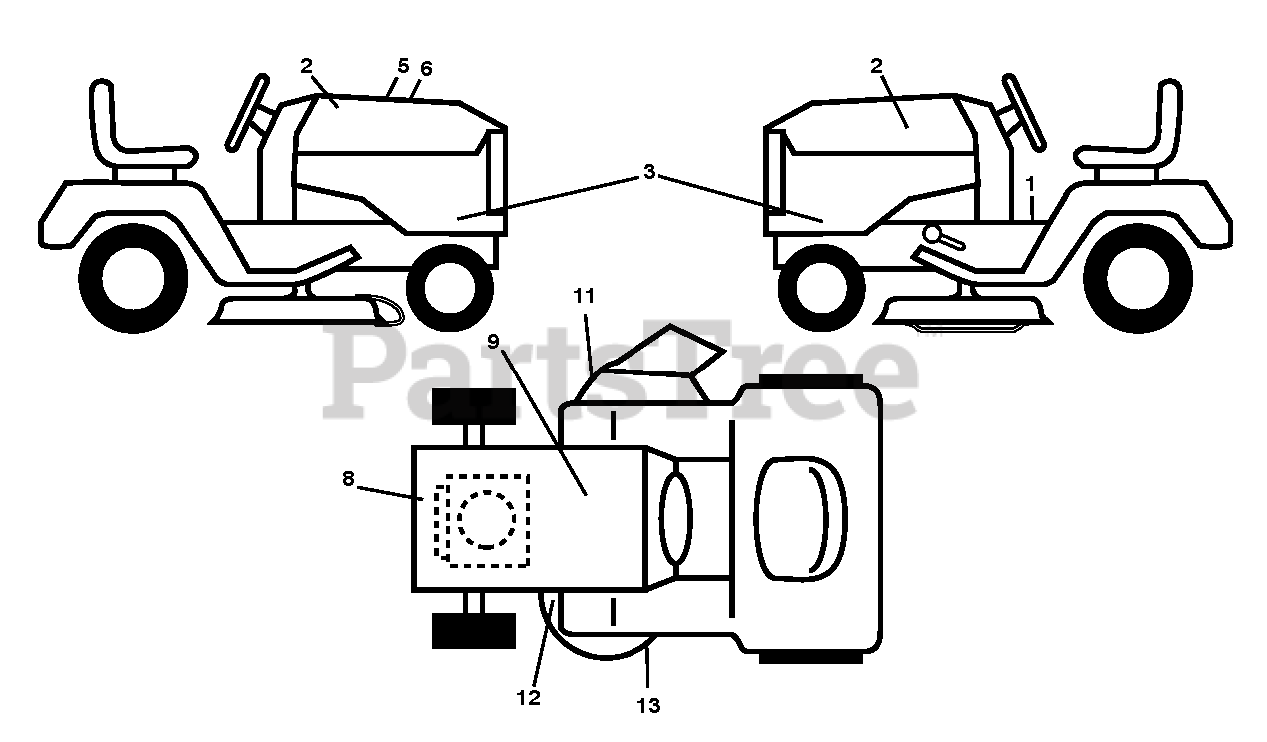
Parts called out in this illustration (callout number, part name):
1	DECAL.FENDER.WARNING
2	DECAL.BADGE.170MM.TEXTLOGO.
5	DECAL.WARNING.CUST.RESP.E85.
8	DECAL.ENG.BS.23HP.XRD.TWIN
9	DECAL BTRY SYMBOLS
11	DECAL.WARN.KEEP.HAND.AWAY
12	DECAL.MOWER
13	DECAL.MOWER.SCH.48/54
